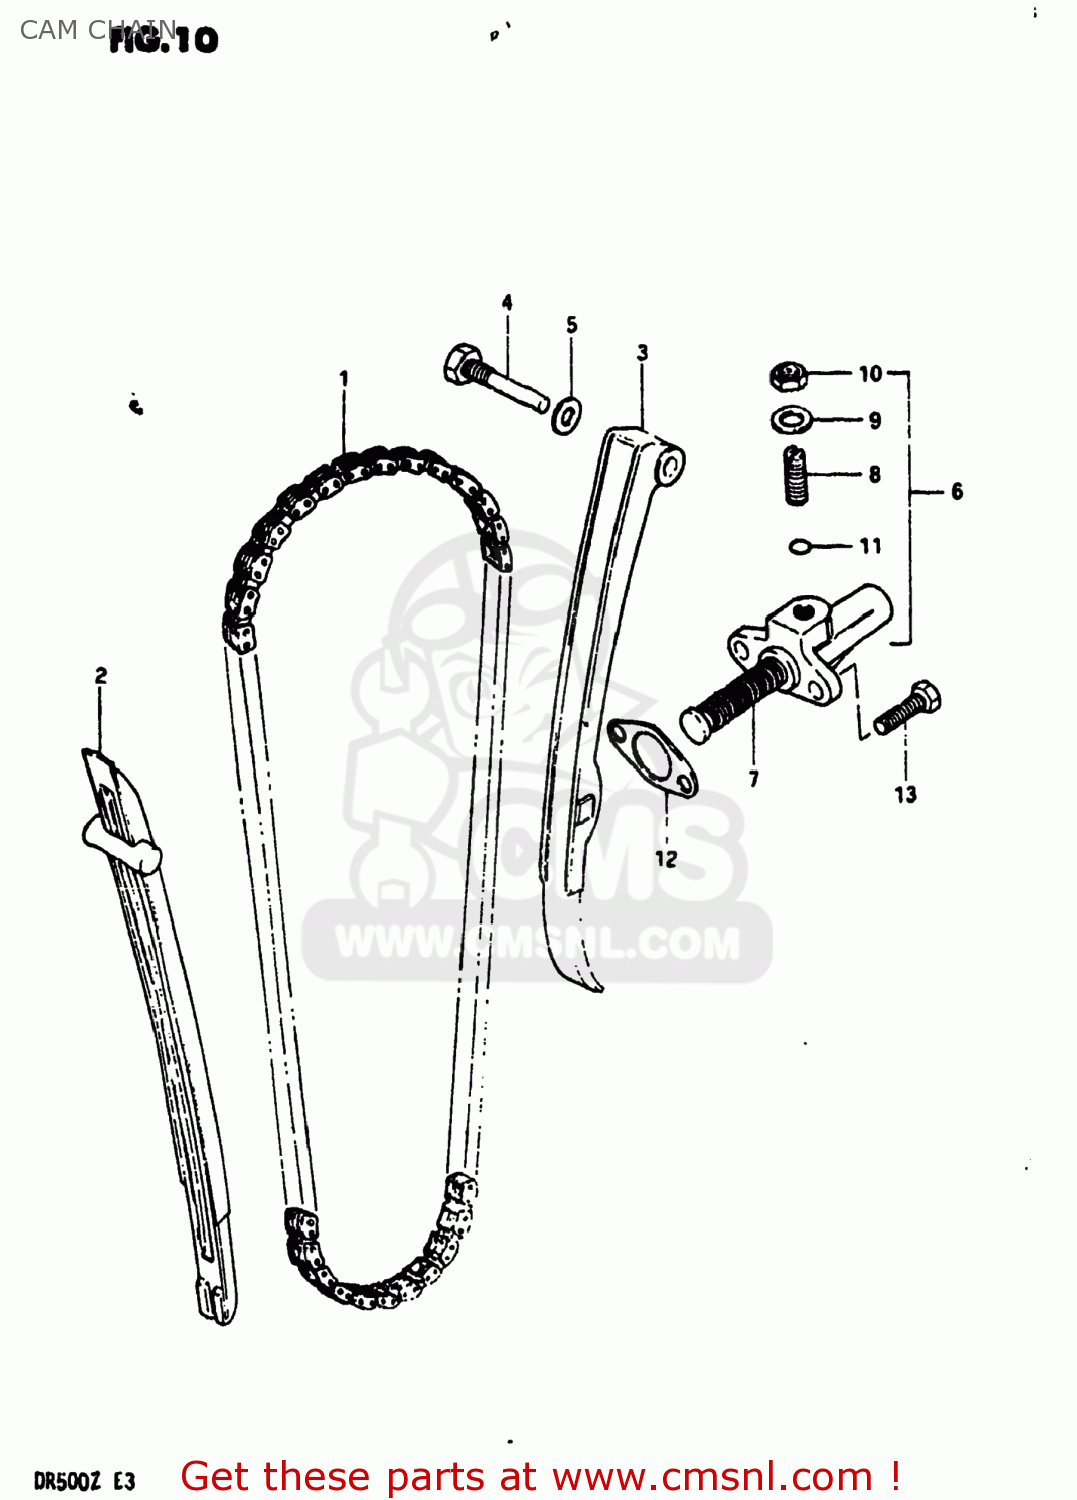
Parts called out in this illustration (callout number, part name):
1	CHAIN,CAMSHAFT DRIVE
2	GUIDE,CAM CHAIN
3	TENSIONER,CAM CHAIN
4	BOLT,CAM CHAIN TENSIONER
5	GASKET 8.2X14X1 (NAS)
6	ADJUSTER ASSEMBLY,TENSIONER
7	SPRING
8	SCREW
9	WASHER
10	NUT
11	O-RING
12	GASKET,TENSIONER ADJUSTER (NAS)
13	BOLT
